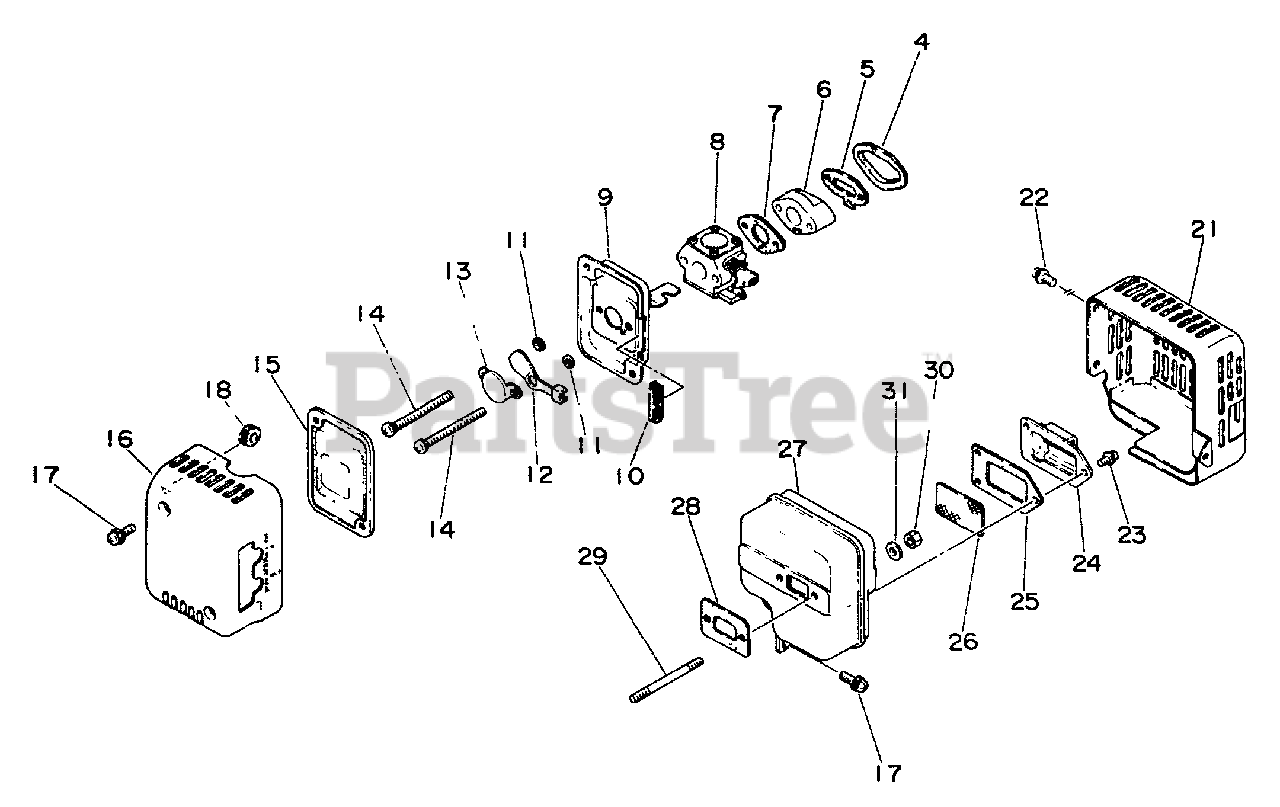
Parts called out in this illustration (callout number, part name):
5	GASKET, INTAKE
6	INSULATOR, INTAKE
7	GASKET, INTAKE
8	CARBURETOR WA-141
9	CASE, AIR FILTER
11	WASHER - 5
12	SHUTTER, CHOKE
13	PLATE, PREVENT
14	SCREW - 5X60
15	FILTER, AIR
16	COVER, AIR FILTER
17	SCREW - 5X14
21	COVER, MUFFLER
22	SCREW - 5X10
23	SCREW - 4X8
24	GUIDE, EXHAUST
25	GASKET, EXHAUST
26	SCREEN, SPARK ARRESTOR
27	CASE, MUFFLER
28	GASKET, EXHAUST
30	LOCKNUT - 5
31	WASHER - 5
